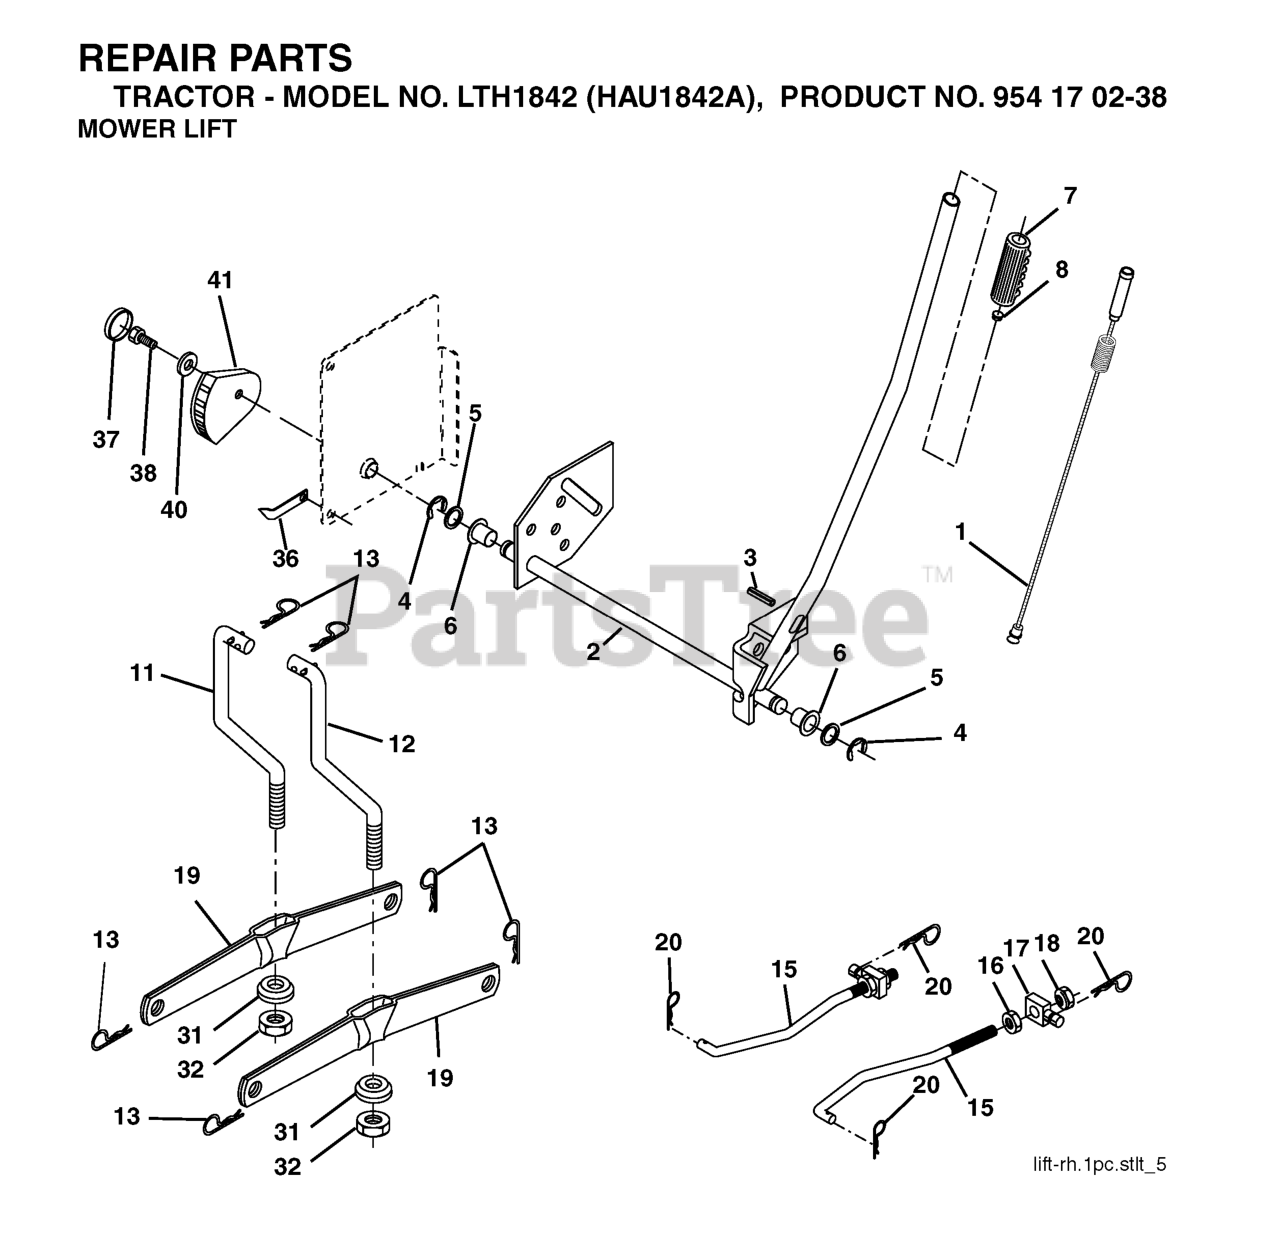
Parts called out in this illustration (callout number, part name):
1	WIRE ASM INNER W/ PLUNGER LT
2	SHAFT ASM R HANDLE
3	PIN GROOVE.
4	RETAINING RING LT
6	BEARING.NYLON
7	GRIP HANDLE
8	PLUNGER BUT KIT
11	LINK LIFT LH
12	LINK LIFT RH
13	RETAINER-SPRNG RB
15	LINK.SUSPENSION.FRONT
16	NUT.HEX.JAM.1/2-13
18	NUT.LK.W/WSH.1/2.
19	ARM.REAR.SUSPENSION
20	SPRING RETAINER
31	BEARING.PIVOT.LIFT
32	NUT CROWNLOCK 3/8-24
36	POINTER, HEIGHT INDICATOR(2 2)
38	SCREW 5/16-18X1
41	IND. HEIGHT STLT
